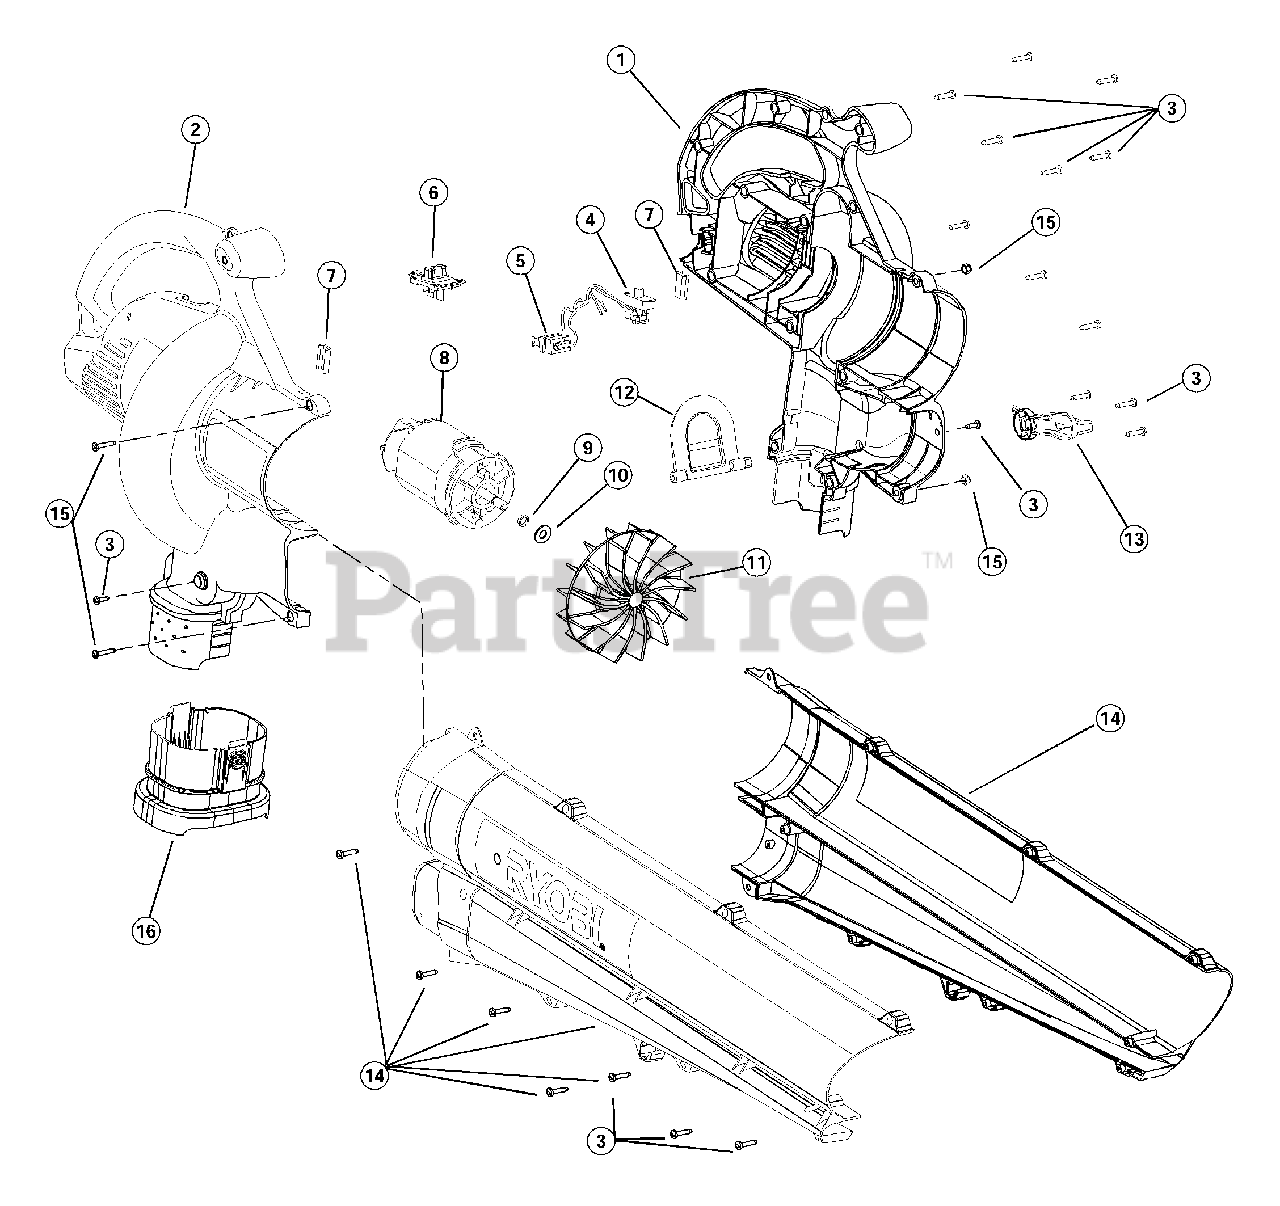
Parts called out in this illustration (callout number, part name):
1	Left Motor Housing
2	Right Motor Housing
3	Housing Screw
4	Switch Assembly
5	Power Connection Wire Assembly
6	Switch Lever
7	Rubber Cushion
8	Motor Assembly
11	Impeller
12	Mode Control Flapper
13	Mode Control Lever
14	Blower/Vac Tube Assembly
15	Blower/Vac Tube Mounting Hardware
16	Vacuum Bag Adapter
